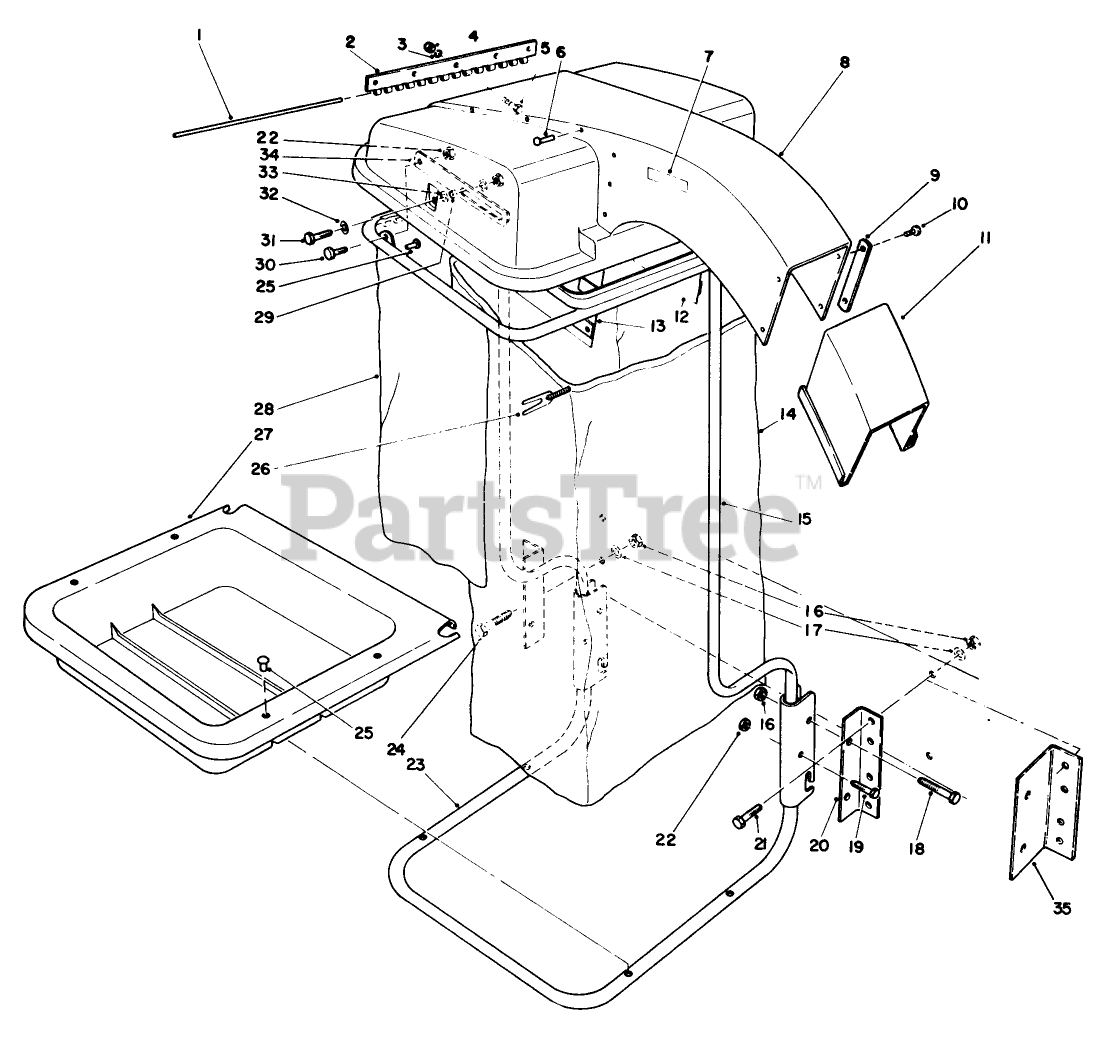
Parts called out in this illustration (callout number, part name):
1	HOOD HINGE PIN
2	Hinge Half
3	WASHER-FLAT
4	NUT-LOCK, NI
6	RIVET-BLIND
7	Decal-Caution
8	Hood Assembly (Incl. Ref. #7)
9	PLATE-NUT B
10	SCREW-HSBH
11	Extension-Snout
12	Screen Left Hand
13	Screen Right Hand
14	BAG-CLOTH, 32"
15	Upper Support Tube Assy. (Incl. Ref. #25 & 28)
16	NUT-LOCK, CONE
17	WASHER-FLAT
18	SCREW-HH
19	SCREW-HH
20	BRKT-FRAME B
21	SCREW-HH
22	NUT-LOCK, CONE
23	Lower Support Tube Assy. (Incl. Ref. #25 & 27)
24	SCREW-HH
26	BAG CORD FASTENER
27	Tray-Lower
28	Skirt-Bagging Frame
29	SPACER - PIVOT ARM
30	SCREW-HH
31	SCREW-HH
32	WASHER-FLAT
33	WASHER-FLAT
34	Stop-Hood
35	Bracket-Frame (Use with 62" Blower Kit
